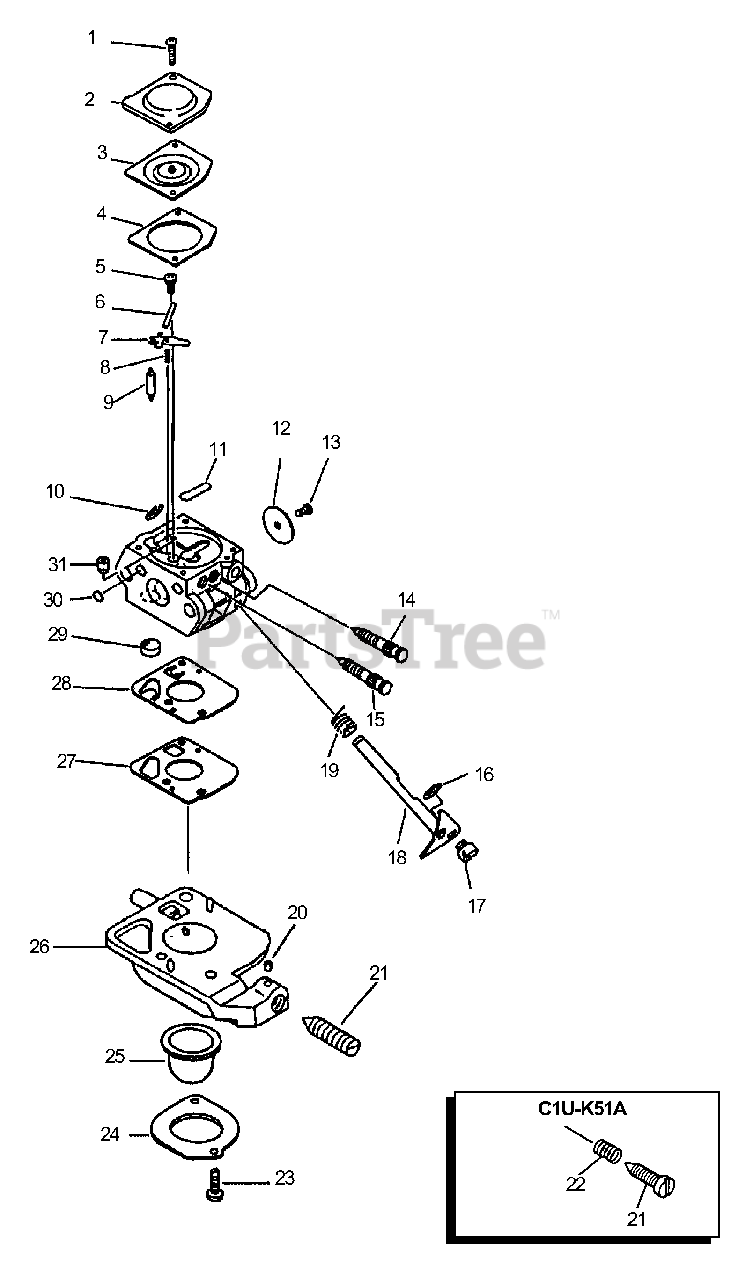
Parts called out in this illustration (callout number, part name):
2	COVER, METERING DIAPHRAGM
3	DIAPHRAGM, METERING
4	GASKET, METERING
6	PIN, METERING LEVER
7	LEVER, METERING
8	SPRING, METERING LEVER
9	VALVE, NEEDLE
11	PLUG, WELCH
12	VALVE, THROTTLE
14	NEEDLE, MIXTURE
15	NEEDLE, HIGH SPEED
18	SHAFT, THROTTLE
19	SPRING, THROTTLE RETURN
20	PIECE, FRICTION
21	SCREW, THROTTLE ADJUST
21	SCREW, IDLE ADJUST
22	SPRING
24	RETAINER
25	BULB, PURGE
26	BODY ASSY, PURGE
29	STRAINER
30	PLUG, WELCH
31	NOZZLE, CHECK VALVE
